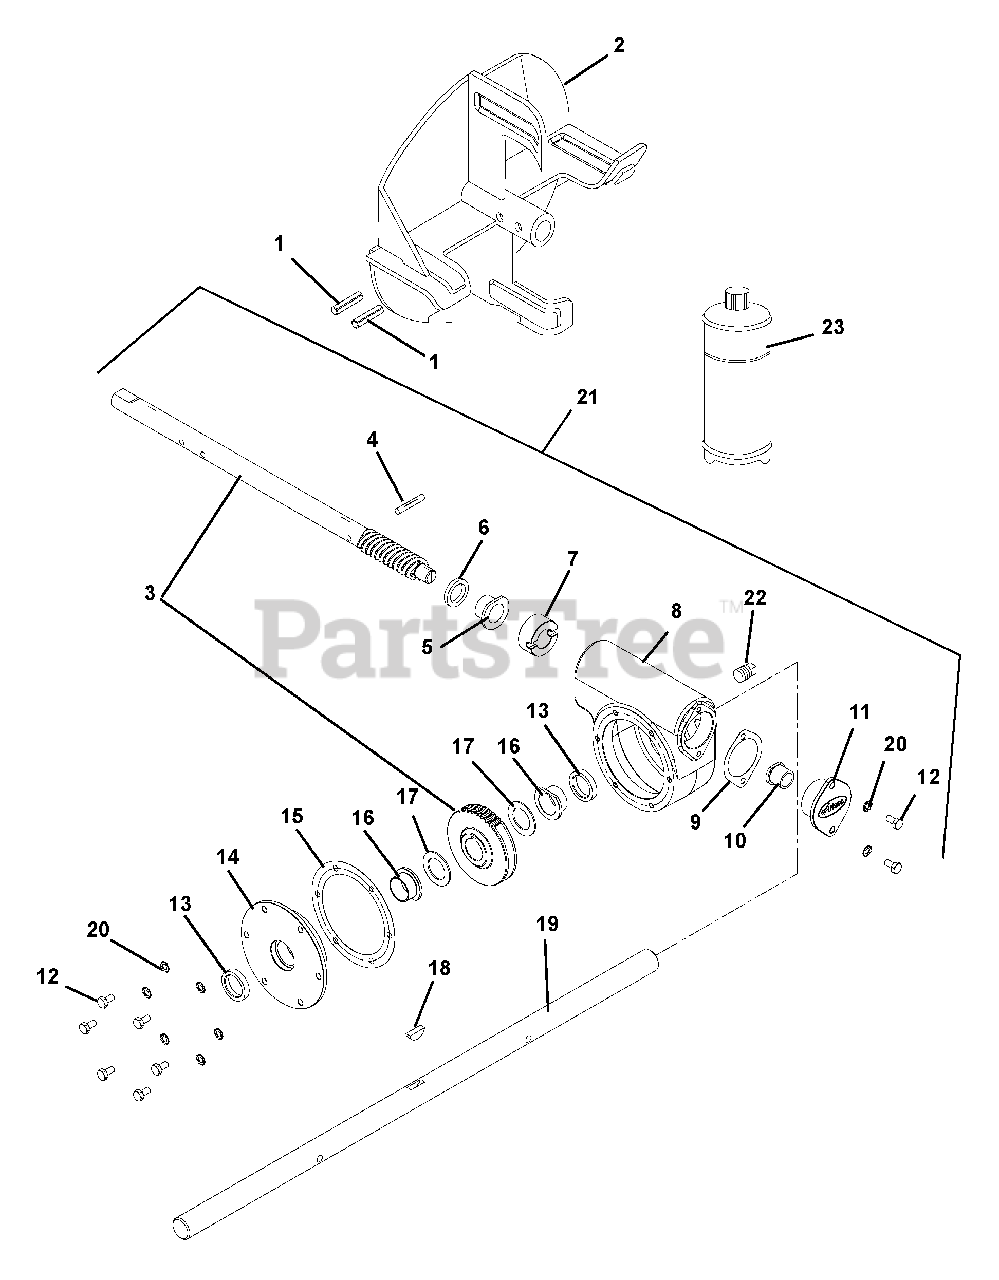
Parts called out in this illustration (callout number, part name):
1	PIN-ROLL .250X1.75
2	IMPELLER-14" 4 BLADE
2	IMPELLER-14" 6 BLADE
3	ASSY, WORM SHAFT & GEAR
4	PIN-GRV .250X1.50 TP E
5	BSHG-FLG .876 X 1.500 X .750
6	SEAL-OIL .875X1.25X.188
7	THRUST COLLAR, .875" ID
8	GEARCASE, CAST IRON-MACHINED
9	GASKET, FRONT - CAST IRON
10	BSHG-FLG .629 X 1.000 X .750
11	COVER, FRONT-CI GEARCASE
12	@BLT-HEX .25-20X.50 GR5 YWZC
13	SEAL-OIL 1.000X1.375X.250
14	COVER, SIDE-CI GEARCASE
15	GASKET, SIDE - CAST IRON
16	BSHG-FLG 1.003X1.5X.625
17	WSHR-HRD-THRS 1.007X1.542X.062
18	KEY-WDRF .25X.875X.375 SAE A
19	SHAFT, RAKE-26"
19	SHAFT, RAKE-28"
19	SHAFT, RAKE-32"
19	SHAFT, RAKE-36"
20	@WSHR-LK-EXT.262X.502X.026YWZC
21	GEAR CASE, CAST IRON-26"
21	GEAR CASE, CAST IRON-28"
21	GEAR CASE, CAST IRON-32"
21	GEAR CASE, CAST IRON-36"
22	PIPE PLUG, 1/4 NPT
23	ARIENS 16 OZ.BOTTLE OF L2 LUBE
